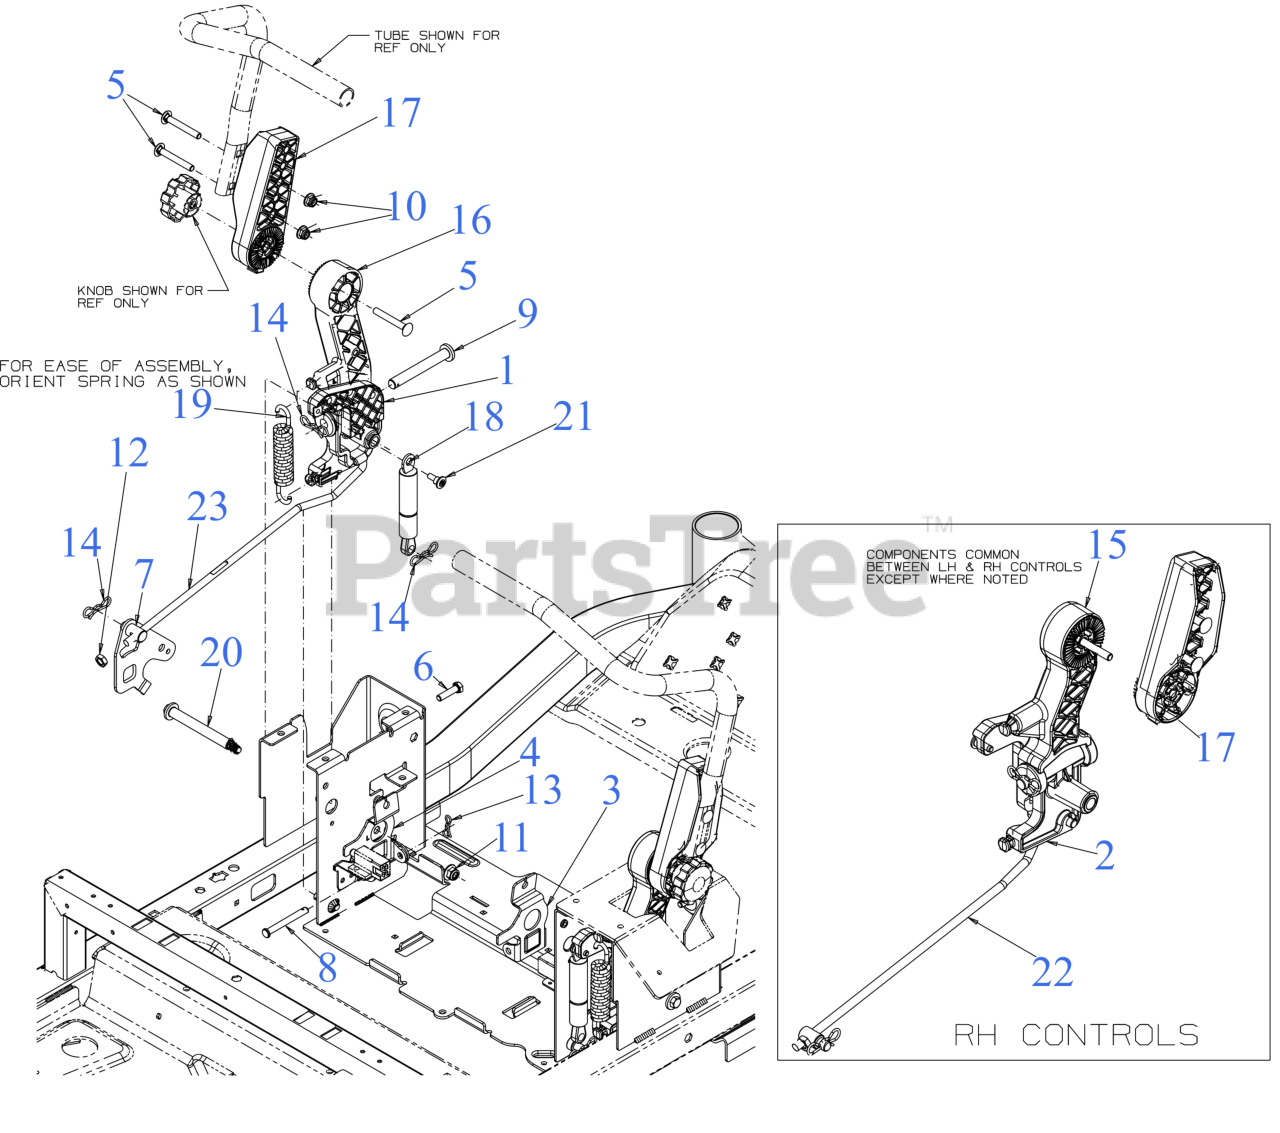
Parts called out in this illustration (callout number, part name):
1	CONTROL ACTUATOR (LH)
1	FLANGE BUSHING
2	CONTROL ACTUATOR (RH)
2	FLANGE BUSHING
3	BRAKE CABLE LEVER (RH)
4	BRAKE CABLE LEVER (LH)
5	BOLT 5/16-18 x 2.50 GR1
6	SCREW 5/16-18 x 1.25 GR5
7	CONTROL ROD FERRULE
8	CLEVIS PIN 5/16 DIA
9	CLEVIS PIN
10	FLANGE LOCK NUT 5/16-18
12	HEX JAM NUT 3/8X24
13	BOW TIE COTTER PIN 1/4-5/16
14	BOW TIE COTTER PIN
15	LAPBAR ACTUATOR (RH)
16	LAPBAR ACTUATOR (LH)
17	UPPER ADJUSTMENT HANDLE
18	DAMPNER CYLINDER
19	EXTENSION SPRING .57 x 5.38
20	SHOULDER SCREW .491x3.937 3/8-16
21	SHOULDER SCREW .394X.280:1/4-14
22	HYDRO CONTROL ROD (RH)
23	HYDRO CONTROL ROD (LH)
